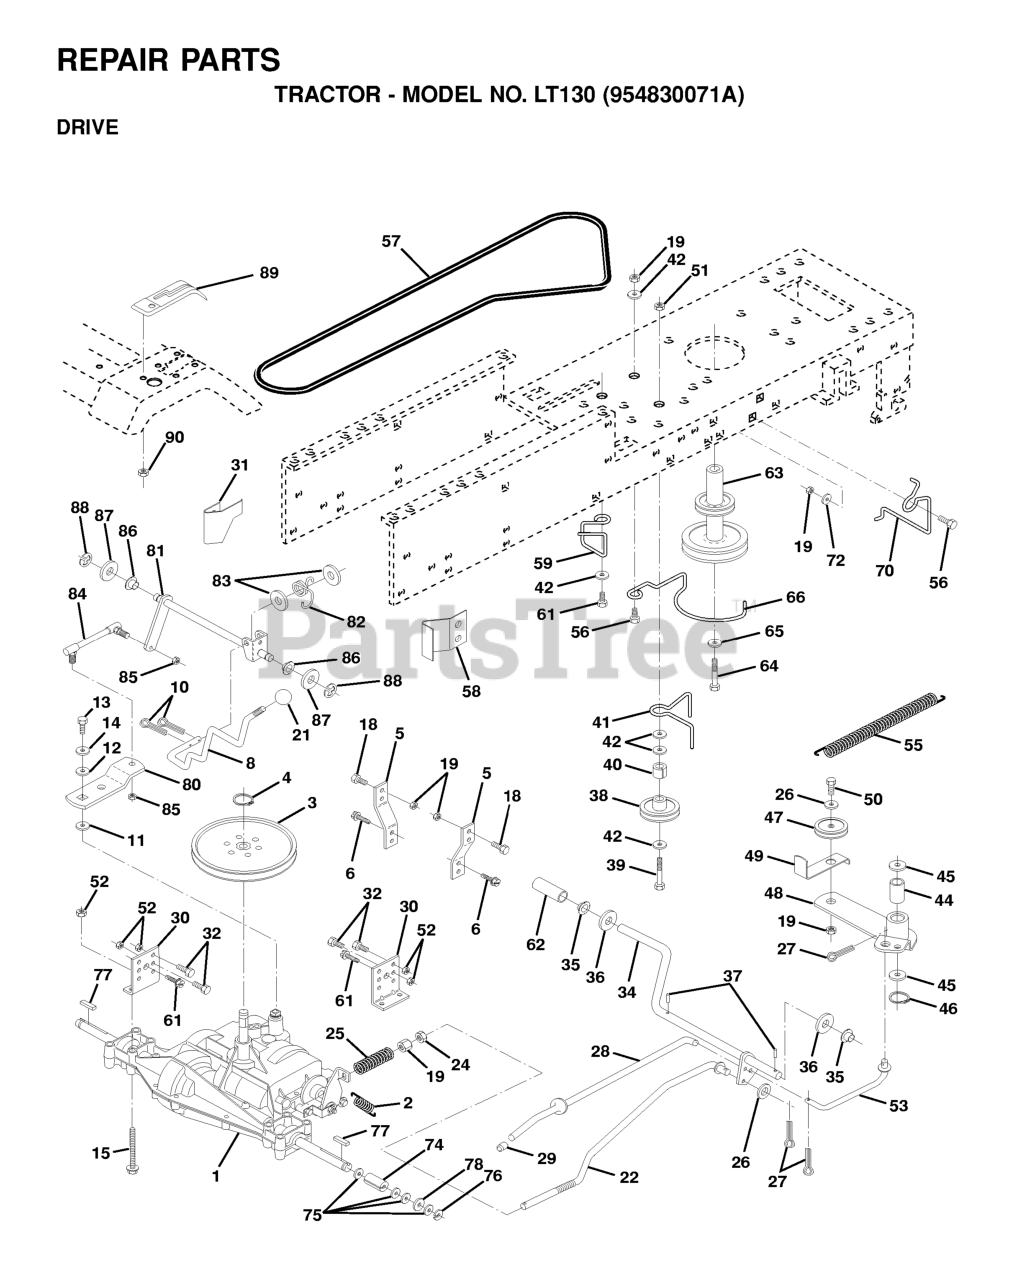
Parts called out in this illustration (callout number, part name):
1	TRANSAXLE
2	SPRING,BRAKE RETURN
3	PULLEY TRANS
4	RETAINING RING LT
5	BOLT HEX 5/16-18 GR 5
6	SCREW.THDROL.5/16-18X3/4.TTY
10	PIN COTTER
11	WASH-SHFT PLT LT
12	Washer 15/32 x 3/4 x 16 Gauge
13	BOLT 1/4-28X3/4
14	LOCKWASHER
15	BOLT HEX 5/16-18 GR 5
19	NUT
21	KNOB.DUCKHEAD.1/2
24	NUT
25	SPRING ROD LT
26	WASHER
27	COTTER PIN
28	ROD BRAKE PARK LT
29	PLUNGER CAP
30	BRACKET TRANSAXLE
31	KEEPER BELT LH
32	BOLT
34	SHAFT PEDAL FOOT
35	BEARING.NYLON
37	DRIVE PIN
38	PULLEY.IDLER.FLAT
41	BELT KEEPER LT NLA
42	WASHER
44	BEARING LT (2 2)
47	IDLER PULLEY
49	RETAIN BELT
50	BOLT
52	LOCKNUT
53	LINK, CLUTCH LT
55	SPRING, RETURN LT
57	V-BELT
59	KEEPER CENTER SPAN
61	SCREW
62	PEDAL COVER T
63	PULLEY.ENG.CL.MECH.SLVR.LT/YT
64	BOLT
65	LOCKWASHER
66	KEEPER, BELT
70	KEEPER BELT ENG
72	WASHER
77	SQUARE KEY
82	SPRING,TORSION
83	WASHER
85	NUT 1/4-28
86	BUSHING.STEERING.ROD LTB-WSL
90	NUT.PUSH.3/16
